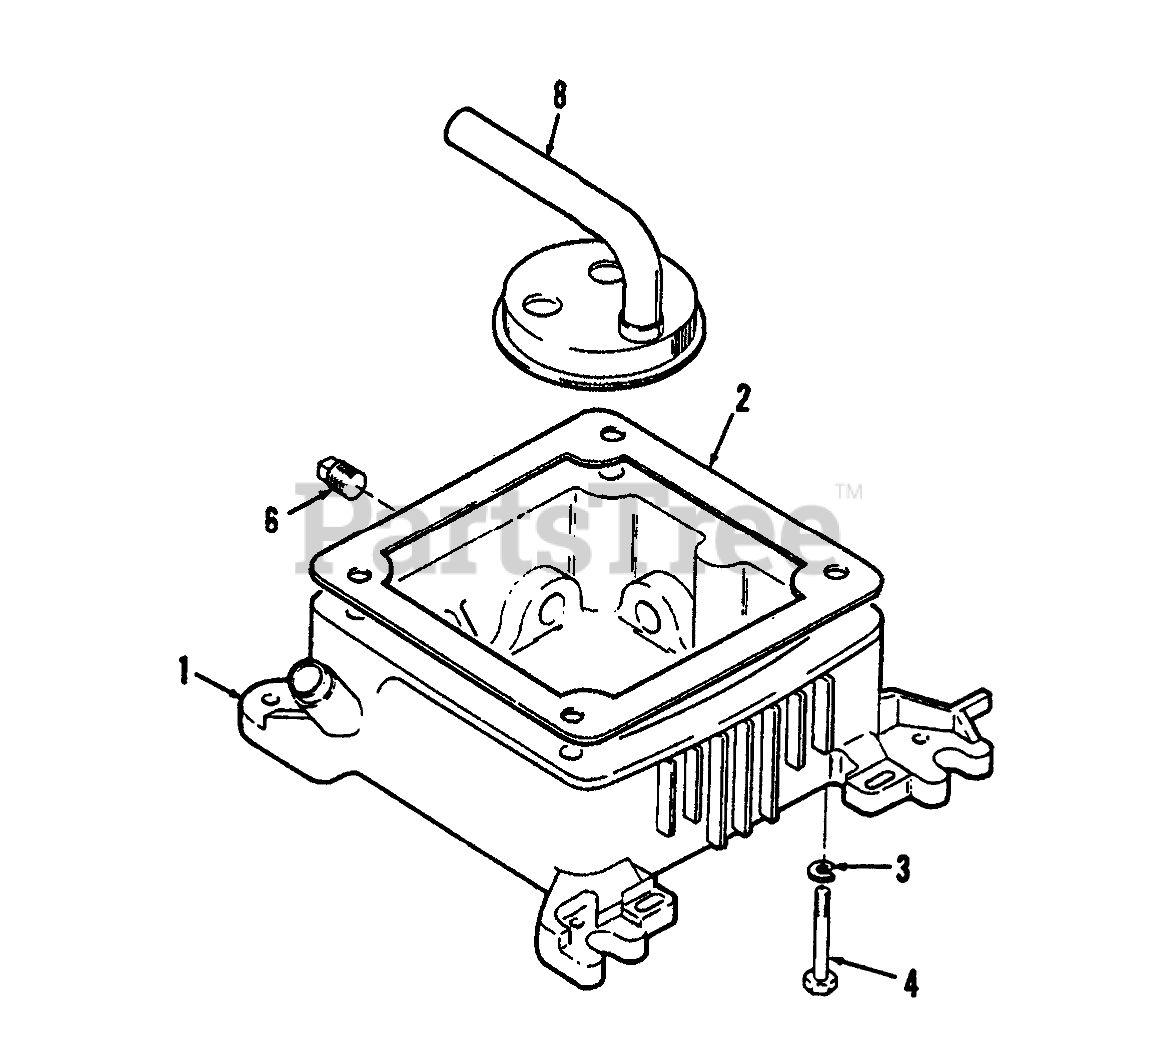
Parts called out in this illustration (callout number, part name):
1	Base-Oil (Includes All Plugs & Plug Gasket)
2	GASKET
3	WASHER-FLAT
4	HHCS 3/8-16 X 3 3/4
6	PLUG - SQUARE HEAD
8	Cup-Oil Pump Intake
